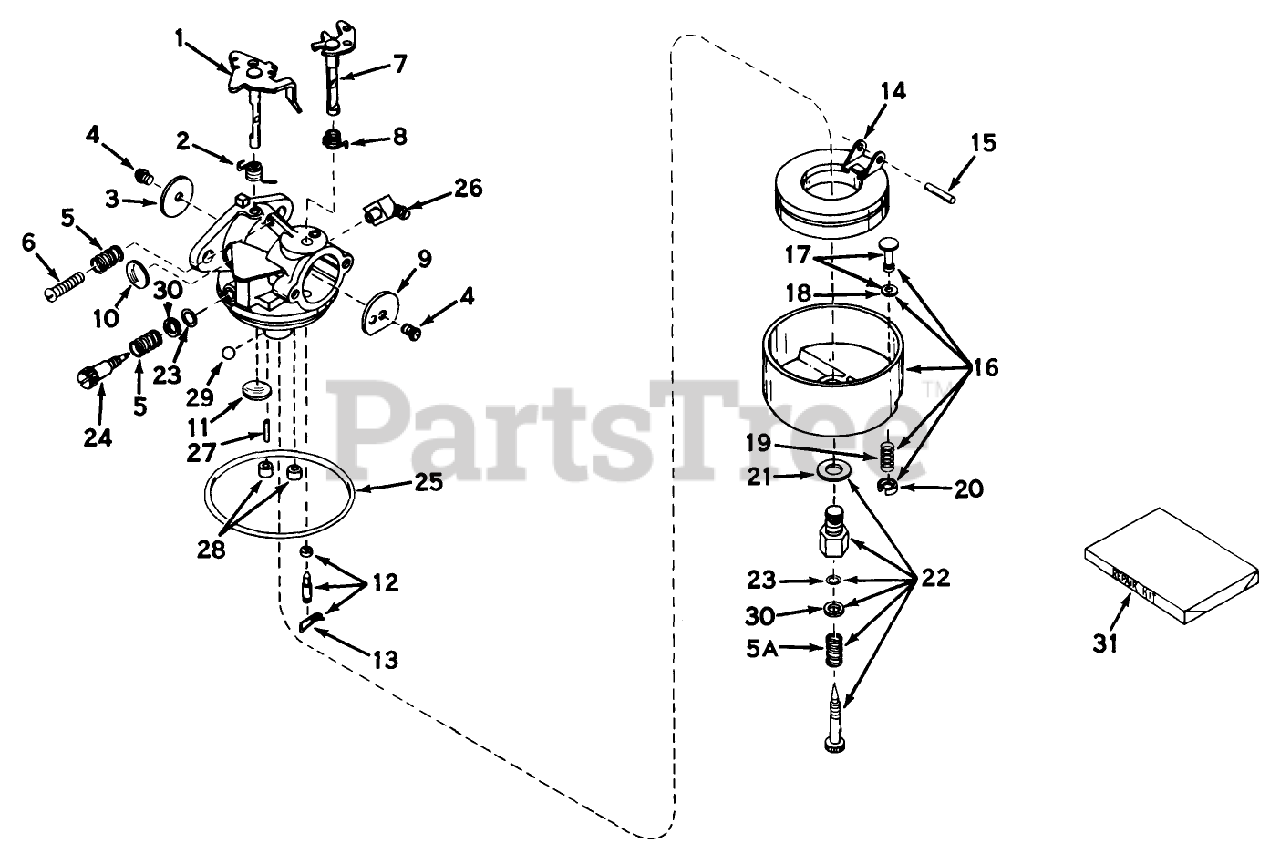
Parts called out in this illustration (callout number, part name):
1	Shaft/Lever-Throttle
2	Spring, Return
3	Shutter-Throttle
4	Screw-Shutter
5	Spring-Tension
5A	Spring
6	Screw-Throttle Crack Screw / Idle Speed
7	Shaft Lever Assy., Choke
8	Spring, Choke return
9	Shutter-Choke
10	Plug-Welch, Idle Mixture Well
11	Plug-Welch, Atmospheric Vent
12	Inlet Needle, Seat Clip Assy. (Incl. No. 13)
13	Clip-Spring
14	Float,Carburetor
15	Shaft-Float
16	Bowl Drain Assy., Float (Incl. No. 17)
17	Plunger Assy., Drain (Incl. Ref. 18)
18	Gasket-Plunger, Drain
19	Spring, Drain Plunger
20	Retainer, Plunger Spring
21	Washer-Bowl Nut
22	Adjustment Screw Assy., Main (Incl. Nos. 5A, 21 23)
23	ORing
24	Screw, Idle Adj.
25	O Ring-Bowl, Float
26	Fitting, Fuel Inlet
28	Plug, Cup
29	BalI, Steel
30	Washer
31	Repair Kit
